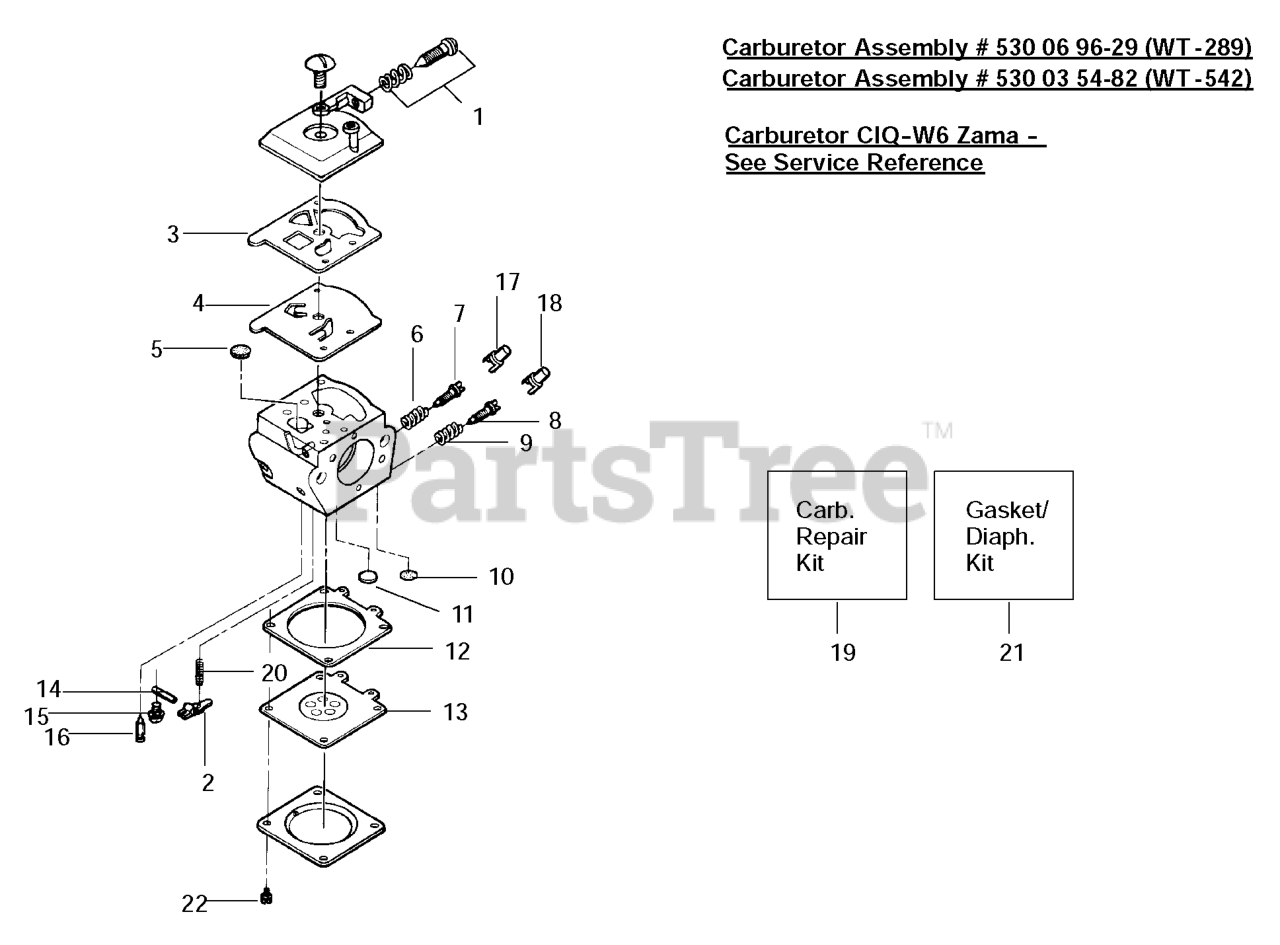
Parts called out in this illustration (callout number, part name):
1	IDLE ADV SCREW KIT
2	LEVER
3	GASKET-FUEL PUMP
4	DIAP FUEL PUMP
5	FILTER SCREEN
6	NEEDLE SPRING
7	LOW SPEED NEEDLE
8	High Speed Needle
9	NEEDLE SPRING
10	Plug-5/16 Dia. Welch
12	METERING DIA GASKET
13	DIAPHRAGM
14	PIN
16	INLET NEEDLEVALVE
17	LIMITER CAP-HIGH
18	LIMITER CAP-LOW
20	SPRING-METERING LEVER
22	SCREW, MOTOR COVER
